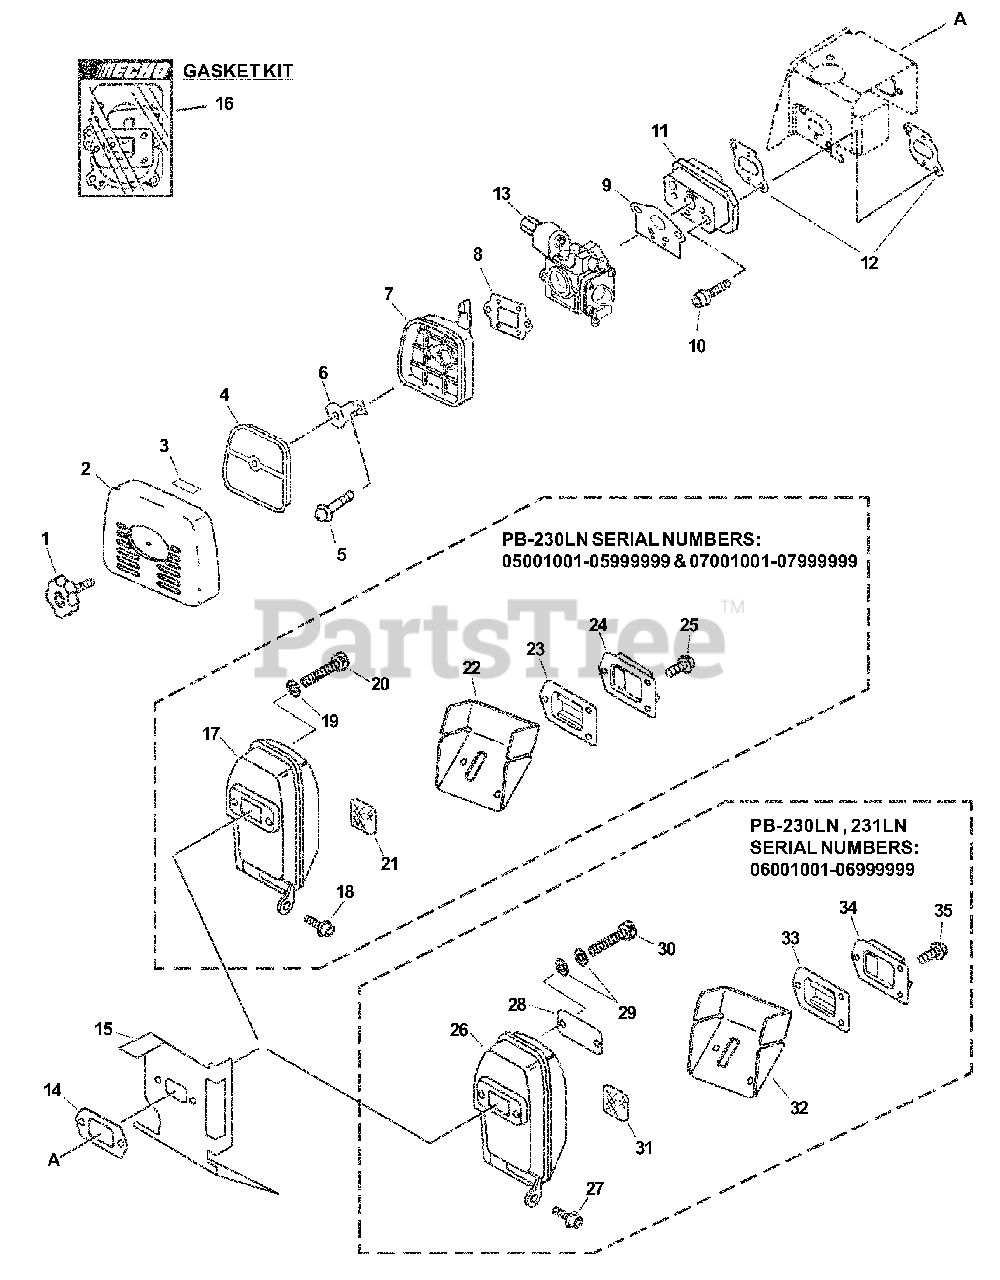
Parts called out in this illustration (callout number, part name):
1	THUMBSCREW
2	COVER, AIR FILTER
3	LABEL - CHOKE
4	FILTER, AIR - HEAVY DUTY
5	SCREW - 5X60
6	PLATE, PREVENT
7	CASE, AIR FILTER
9	GASKET, INTAKE
10	SCREW - 5X25
11	INSULATOR, INTAKE
12	GASKET, INTAKE
13	CARBURETOR
14	GASKET, EXHAUST
15	SHIELD, EXHAUST
16	GASKET KIT
17	MUFFLER
18	SCREW - 5X16
19	WASHER - 5
20	SCREW - 5X60
21	SCREEN, SPARK ARRESTOR
22	GASKET, EXHAUST
23	GUIDE, EXHAUST - INNER
24	GUIDE, EXHAUST
25	SCREW - 4X10
26	MUFFLER
27	SCREW - 5X16
28	PLATE
29	WASHER - CONICAL
30	BOLT - 5X65
31	SCREEN, SPARK ARRESTOR
32	GASKET, EXHAUST
33	GUIDE, EXHAUST - INNER
34	GUIDE, EXHAUST
35	SCREW - 4X12
